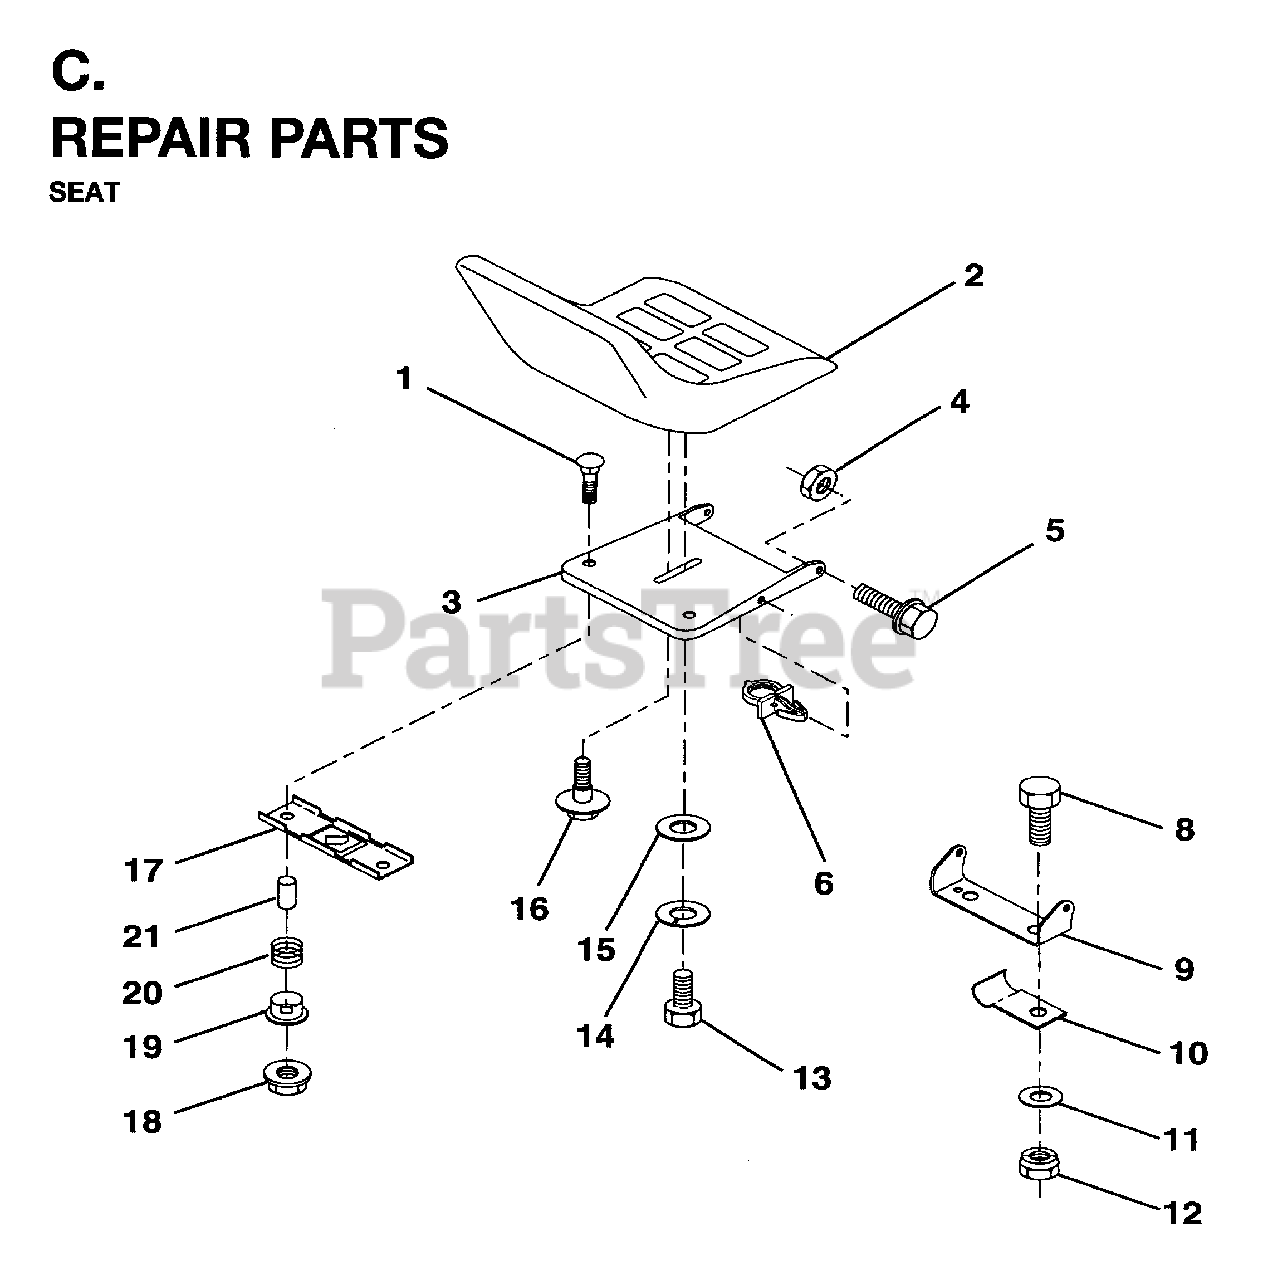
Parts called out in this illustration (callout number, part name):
1	BOLT CARRIAGE 1/4-20X1 3/8
2	SEAT
3	SEAT PAN
4	NUT.71038.31-18.HEX.NYLOCK
6	PUSH CLIP
9	SEAT PIVOT BRKT
10	CLIP,INSULATOR
11	WASHER 12/32X2X10GA
12	LOCKNUT
13	BOLT
14	LOCKWASHER
16	BOLT,SHOULD
17	BRKT SWITCH
18	NUT.CROWNLOCK.1/4
21	SPACER SPLIT 28X.96
